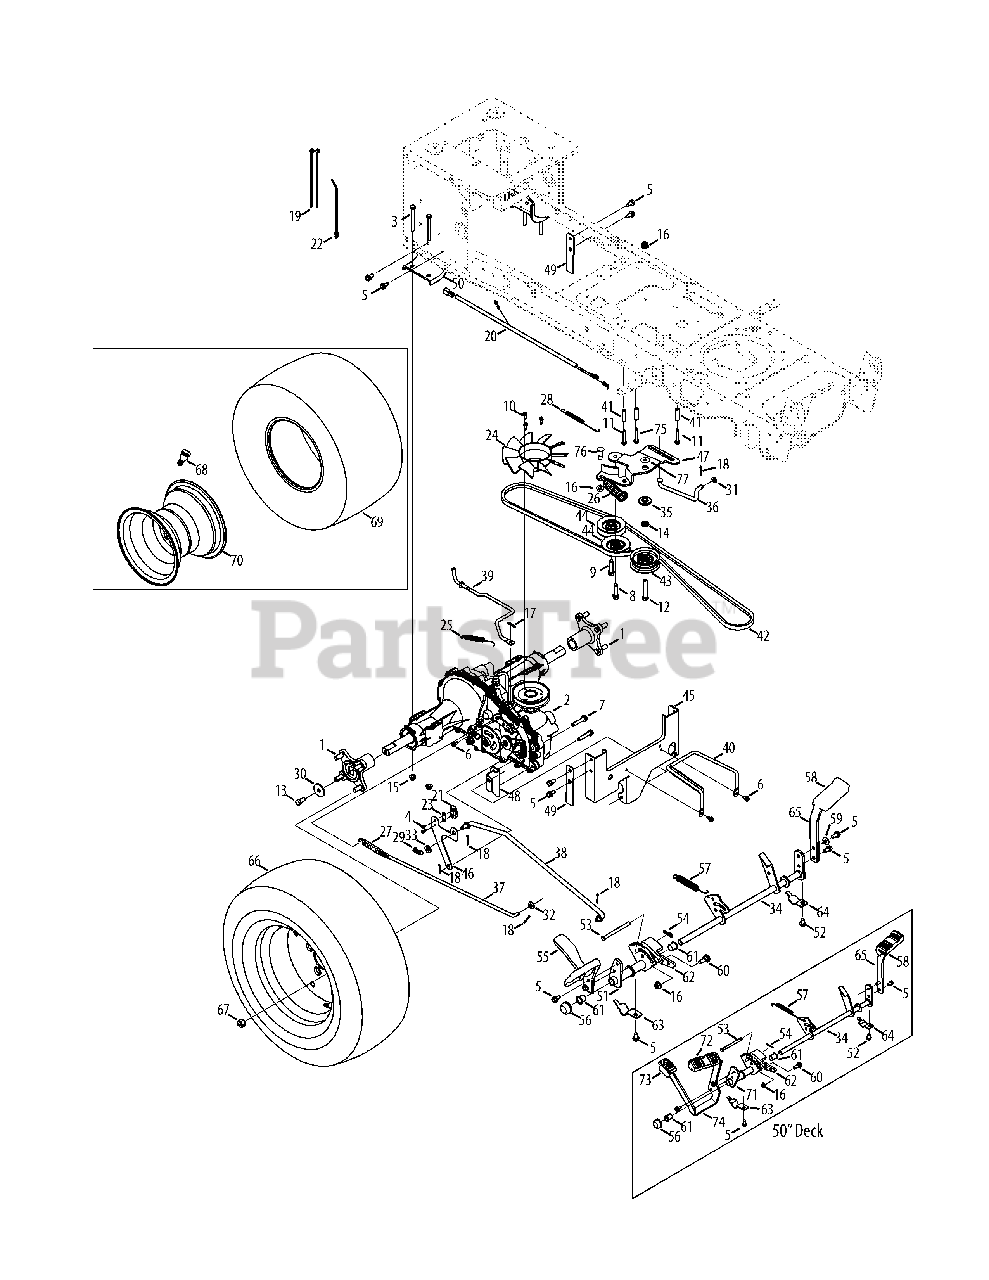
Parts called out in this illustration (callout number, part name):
1	Wheel Assembly Hub
2	Transmission
3	Hex Screw, 5/16-18:3.00
4	Screw, #8-18:0.500
5	Taptite Screw, 5/16-18:.750
6	Taptite Screw, 1/4-20:0.500
7	Taptite Screw, 5/16-18:1.750
8	Taptite Sems Screw, 3/8-16:1.500
9	Taptite Sems Screw, 3/8-16:1.875
10	Screw, #12-24:0.625
11	Taptite Screw, 1/4-20:1.625
12	Hex Screw, 3/8-16:2.25
13	Hex Screw, 3/8-16:.750
14	Jam Nut, 7/16-20
15	Flangelock Nut, 5/16-18
16	Flangelock Nut, 3/8-16
17	Cotter Pin, .072 DIA. x 1.13 LG
18	Cotter Pin, 3/32:1.0
19	Cable Tie, 3/16 x .05 x 7.4
20	Jumper Harness
21	Short Spring Switch
22	Push Mount Cable Tie 7.5 LG
23	Insulator Nut Plate
24	Blade Fan
25	Extension Spring, .50 DIA x 5.0 LG
26	Extension Spring, 1.00 DIA x 4.75
27	Extension Spring, .59 OD x 4.00 LG
28	Extension Spring, .38 DIA x 5.6
29	Extension Spring, .375 OD x 1.44 LG
30	Flat Washer, .390 x 1.500 x .134
31	Flat Washer, .330 x .630 x .0635
32	Flat Washer, .344 x .750 x .120
33	Flat Washer, .407 x .812 x .135
34	Brake Control Assembly
35	Shoulder Spacer, 1.375 x .380 x .183
36	Footpedal Bypass Transmission Rod
37	Brake Rod
38	Control Rod
39	Disengage Rod
40	Belt Keeper, 5/16
41	Spacer, 260 x .372 x 1.420 LG
42	V Belt, 4L x 77.0
43	Flat Idler Pulley, 2.75 OD
44	V Idler Pulley, 3.06
45	Torque Bracket
46	Switch Bracket
47	Center Idler Bracket
48	Deck Bracket
49	Plate Bracket
50	Axle Bracket
51	Hydro Pedal Bracket Assembly
52	Taptite Screw, 5/16-18:0.625
53	Clevis Pin, 5/16 x 3.985
54	Bow-Tie Cotter Pin
55	Control Pedal
56	Push Cap
57	Extension Spring, .63 DIA x 4.95 LG
58	Brake Pedal Pad
59	Bell Washer, .340 x .872 x .060
60	Shoulder Bolt, .500 x .270:3/8-16
61	Flange Bearing, .630 ID x .695 OD x .60
62	Cruise Latch
63	Pedal Support Bracket
64	Pedal Support Bracket, 5/8
66	Wheel Assembly
67	Lug Nut, 7/16-14
68	Air Valve
70	Rim Assembly
71	Hydro Pedal Bracket Assembly
72	Reverse Pedal Pad
73	Forward Pedal Pad
74	Drive Pedal Bracket
75	Taptite Screw, 1/4-20:1.750
76	Screw Shldr, .50 x .685 3/8-16
77	Washer, Flat, .385 x 1.0 x .030
